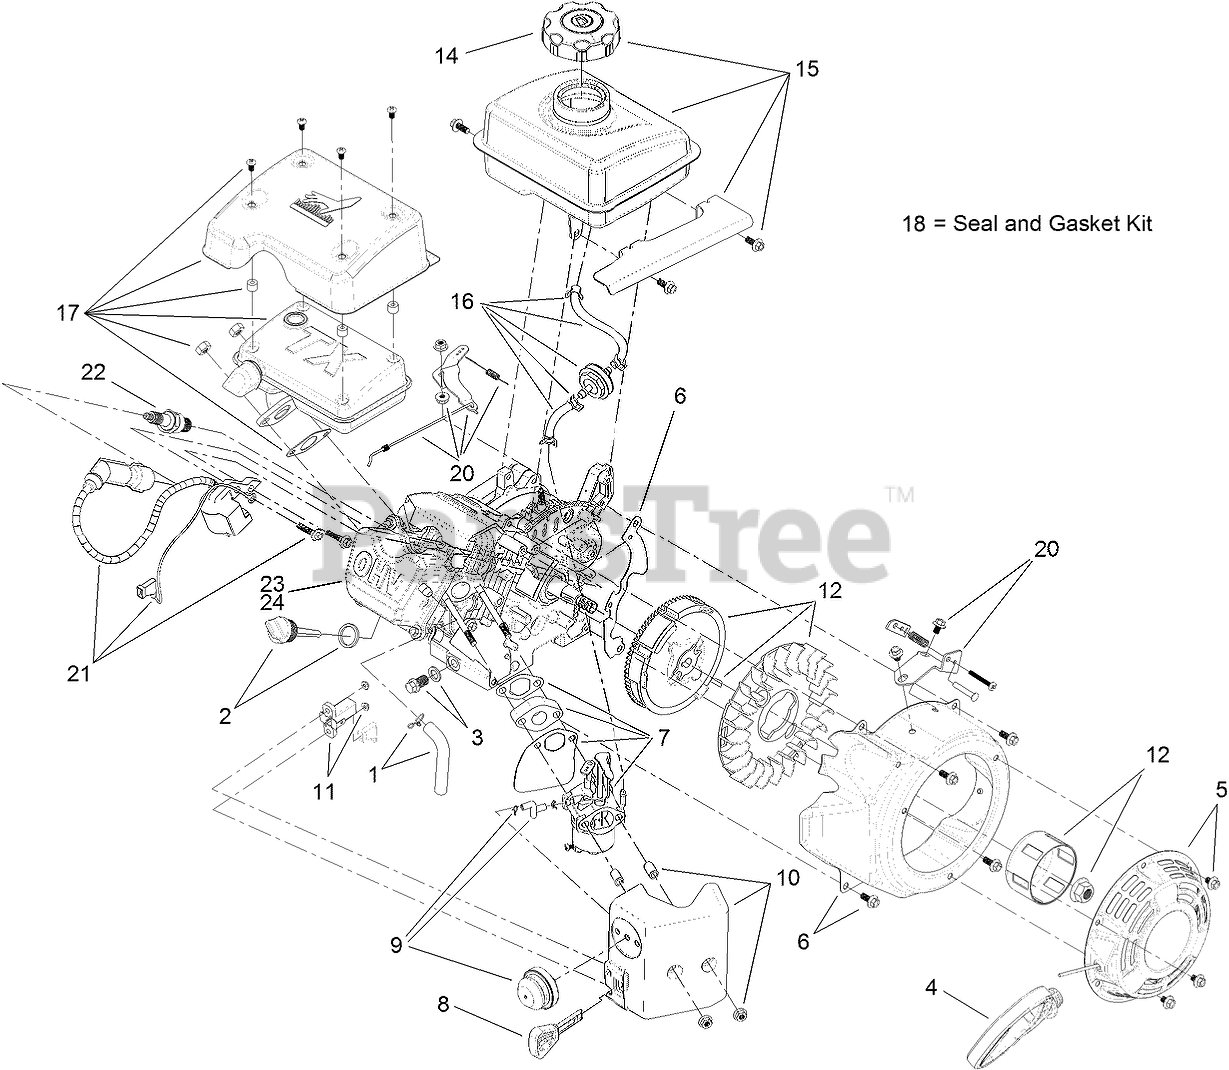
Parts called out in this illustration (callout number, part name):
1	BREATHER TUBE KIT
2	DIPSTICK AND O-RING KIT
3	DRAIN PLUG KIT
4	MITTEN GRIP KIT
5	RECOIL ASM KIT
6	BLOWER SHROUD KIT
7	COMPLETE CARB SERVICE KIT
8	KEY AND LANYARD KIT
9	PRIMER BULB KIT
10	HEATER BOX KIT
11	SWITCH KIT
12	FLYWHEEL AND FAN KIT
14	FUEL CAP ASM KIT
15	FUEL TANK, CAP AND HARDWARE KIT
16	FUEL LINE, FILTER AND CLAMP KIT
17	MUFFLER KIT
20	GOVERNOR ARM, SPRING, LINK, HARDWARE KIT
21	IGNITION KIT
22	SPARK PLUG
23	GASKET-COVER, VALVE
24	VALVE COVER ASM
